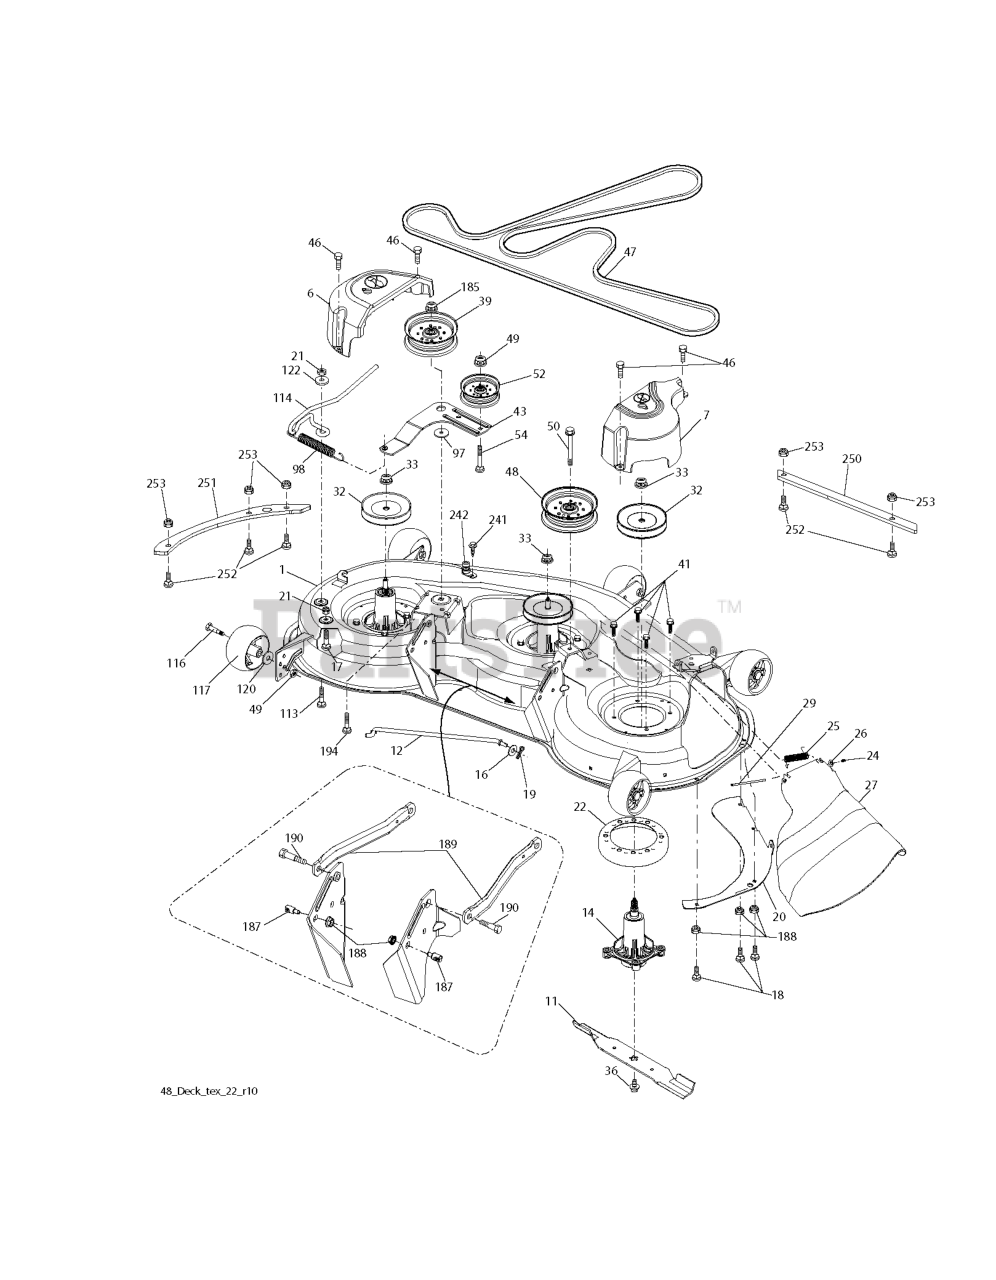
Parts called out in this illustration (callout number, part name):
1	DECK.SVC 48".4GWB.O
6	COVER.MANDREL.LH.48"(2 2)
7	COVER.RH.MANDREL
11	48" HI-LIFT BLADE
12	ROD.ANTI.SWAY.48/54"K4
14	KIT.MANDREL.GREASEABLE.TALL
17	BOLT.CARR.5/16-18X5/8.SHORT
18	BOLT ROUND HEAD SQUARE NECK BO
19	PIN.COTTER.5/16.BOW TI
20	BAFFLE, VORTEX MWR
22	STRIPPER.MANDREL.ROUND.BLACK
24	CAP-SLEEVE LT
25	SPRING, TORSION
26	NUT PUSH M
27	DEFLECTOR SUBS TO 532 180655
32	PULLEY MANDREL
36	SCREW.SEMS.7/16-20X1.HEX.HEAD
39	RB PULLEY.IDLER.4.50/HUB SPEC
41	BOLT.HEX.WASHR.HED.313-18X1.19
46	SCREW.1/4-20X5/8
47	Belts- 197242
48	PULLEY.IDLER.2006
49	NUT LOCK FLG 3/8-16 UNC
50	SCREW TT 3/8-16X2-1/4 UNC
50	SCREW TT 3/8-16X2.31 UNC
52	PULLEY.IDLER.48"PRIMARY
54	GSPW Bolts
98	SPRING, DECK DRIVE
114	ROD.TENSION.RELIEF.TEX (2 2)
117	WHEEL.GAUGE.RALLY
122	BUSHING.RELIEF.TENSION
185	NUT.LOCK.FLANGE.7/16
187	STUD.W/"D"ANTI-ROTATION
189	ARM.RFIXED.MOWER.SUSPNSIONX431
190	BOLT.SHOULDER
194	BOLT.HEX.WASHER.HEAD.7/16-24X
241	SCREW.TT.#10-32X.5.3/8.FLANGE
242	PORT.WASHOUT
250	PLATE.REIN.FRNT.BOLTON.48X431
251	PLATE.REIN.SIDE.BOLT.ON.48X431
252	BOLT CUP HEAD SQUARE NECK 1/4-
253	NUT T
